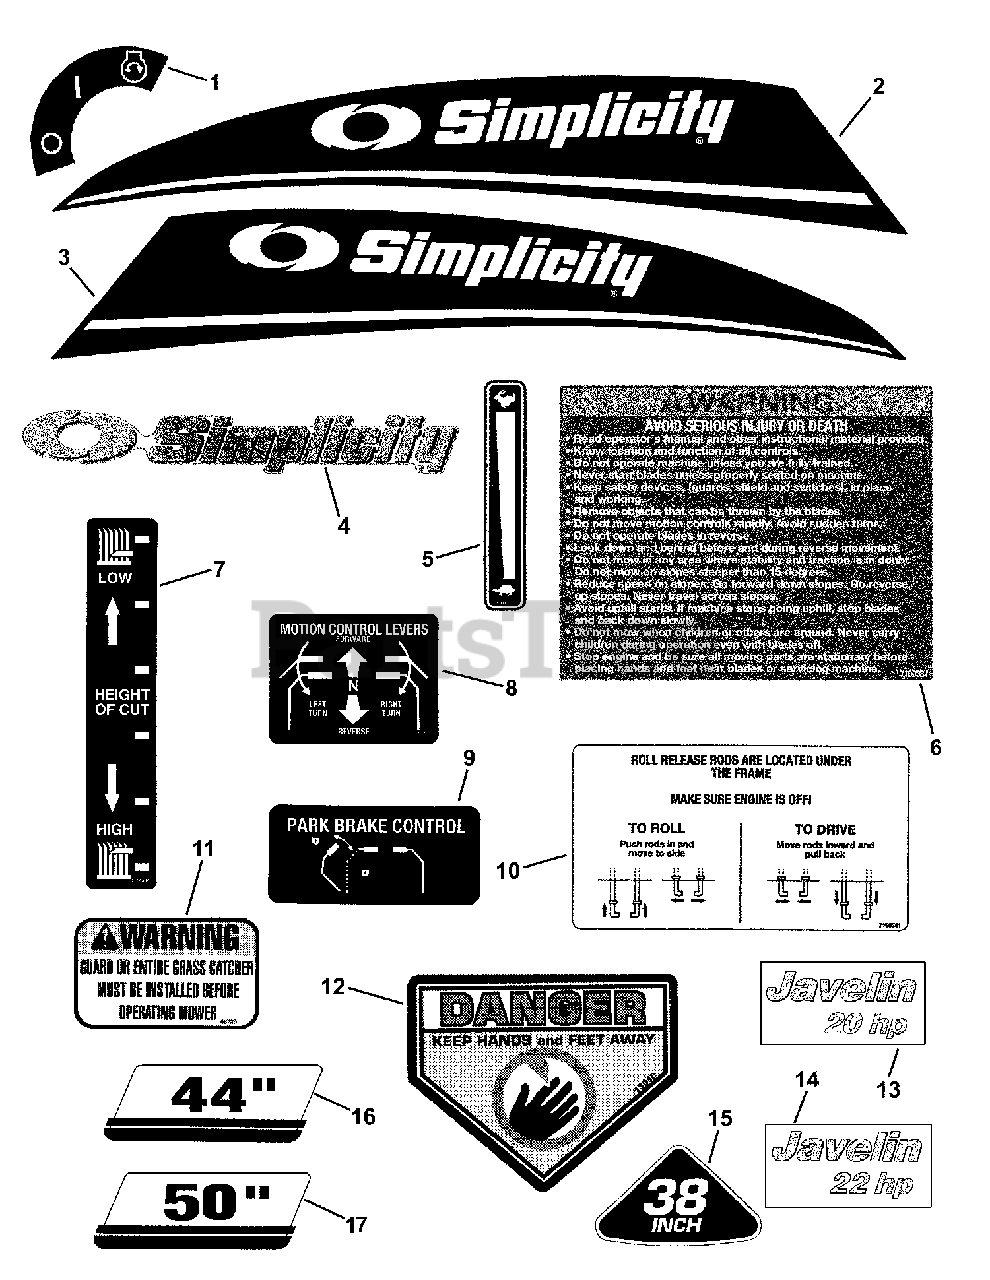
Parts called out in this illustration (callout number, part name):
1	DECAL, Ignition, RZT
2	DECAL, Simplicity Fender, L.H.
3	DECAL, Simplicity Fender, R.H.
4	DECAL, Simplicity Logo
5	DECAL, Throttle Control, RZT
6	DECAL, Warning, Operation
7	DECAL, Height Of Cut, RZT
8	DECAL, Motion Control
9	DECAL, Park Brake
10	DECAL, Roll Release, RZT
11	DECAL, Chute Deflector
12	DECAL, Warning
13	DECAL, Javelin, 20HP
14	DECAL, Javelin, 22HP
16	DECAL, 44", Silver On Black w/Stripe
17	DECAL, 50", Silver On Black w/Stripe
